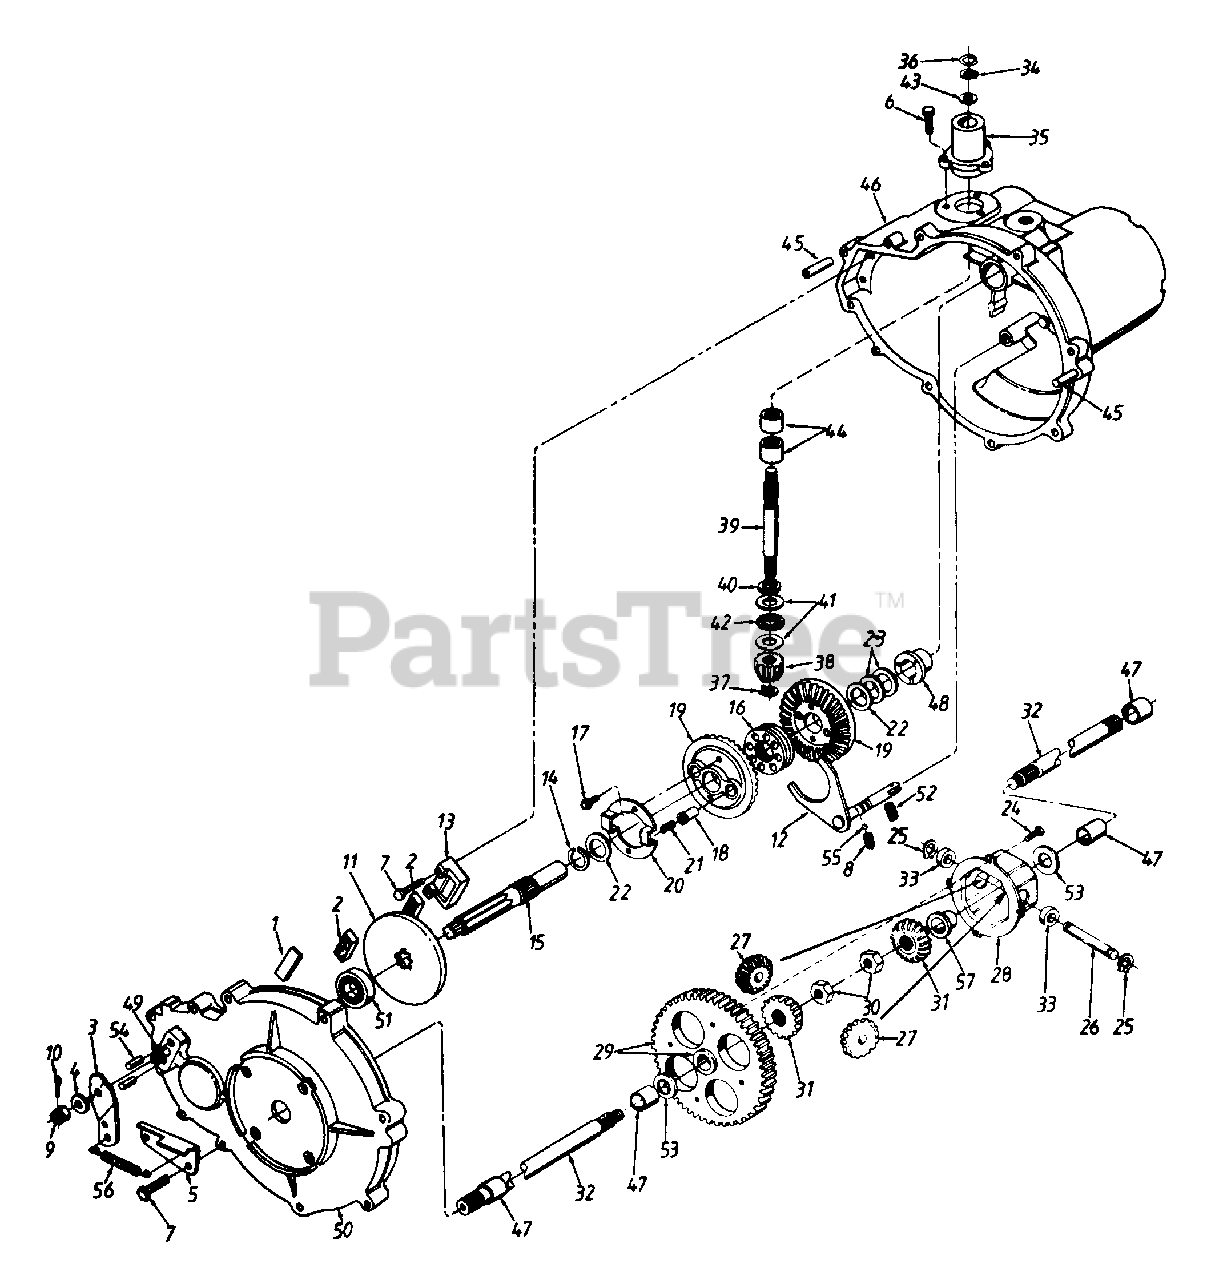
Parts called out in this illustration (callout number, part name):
1	Puck Plate
2	Brake Puck
3	Actuating Arm
4	Fl-Wash. 11/32" I.D. x 7/8" O.D.
5	Brake Stop Brkt.
6	Hex Bolt 1/4-20 x .62" Lg. (Special)
7	Hex Tap Scr. 1/4-20 x 1.25" Lg.
8	Spring Detent
9	Castle Nut 5/16-24 Thd.
10	Cotter Pin 3/32" Dia. x 1" Lg.
12	Shifter Ass'y.
13	Brake Puck Holder
14	Retaining Ring
16	Shift Collar
17	Hex Wash. Hd. Tap Scr. 1/4-20 x .38" Lg.
18	Drive Pin
19	Bevel Gear Ass'y.
20	Spring Retaining Plate
21	Drive Spring
22	Fl-Wash. .915" I.D. x 1.5" O.D.
23	Fl-Wash. .915" I.D. x 1.37" O.D.
24	Pan Hd. Scr. 1/4-20 x .5" Lg.
25	Snap Ring
27	Miter Gear 15T
28	Differential Can Assembly
29	Differential Gear Ass'y. w/Bearing
30	Hex Ins. L-Nut 1/2-20 Thd.
31	Miter Gear
32	Axle
33	Differential Thrust Spacer
34	Retainer Ring
35	Input Bearing Housing
37	Retaining Ring
38	Pinion Input 14T
40	Seal 5/8" I.D.
41	Thrust Wash. .621" I.D. x 1.12"
42	Thrust Bearing
43	Fl-Wash. 5/8" I.D. x 1.0" O.D.
44	Needle Brg. 5/8" x 1/2" Lg.
46	R.H. Housing
47	Sleeve Bearing 3/4" I.D.
48	Flange Bearing .906" I.D.
49	Sq. Head Bolt 5/16-24 Thd.
50	L.H. Housing
51	Ball Bearing .669" I.D.
52	Set Screw 5/16-18 x 3/8" Lg.
53	Fl-Wash. .76" I.D. x 1.5" O.D.
54	Brake Actuating Pin
56	Ext. Spring 1.14" Lg.
57	Differential Flange Brg.
